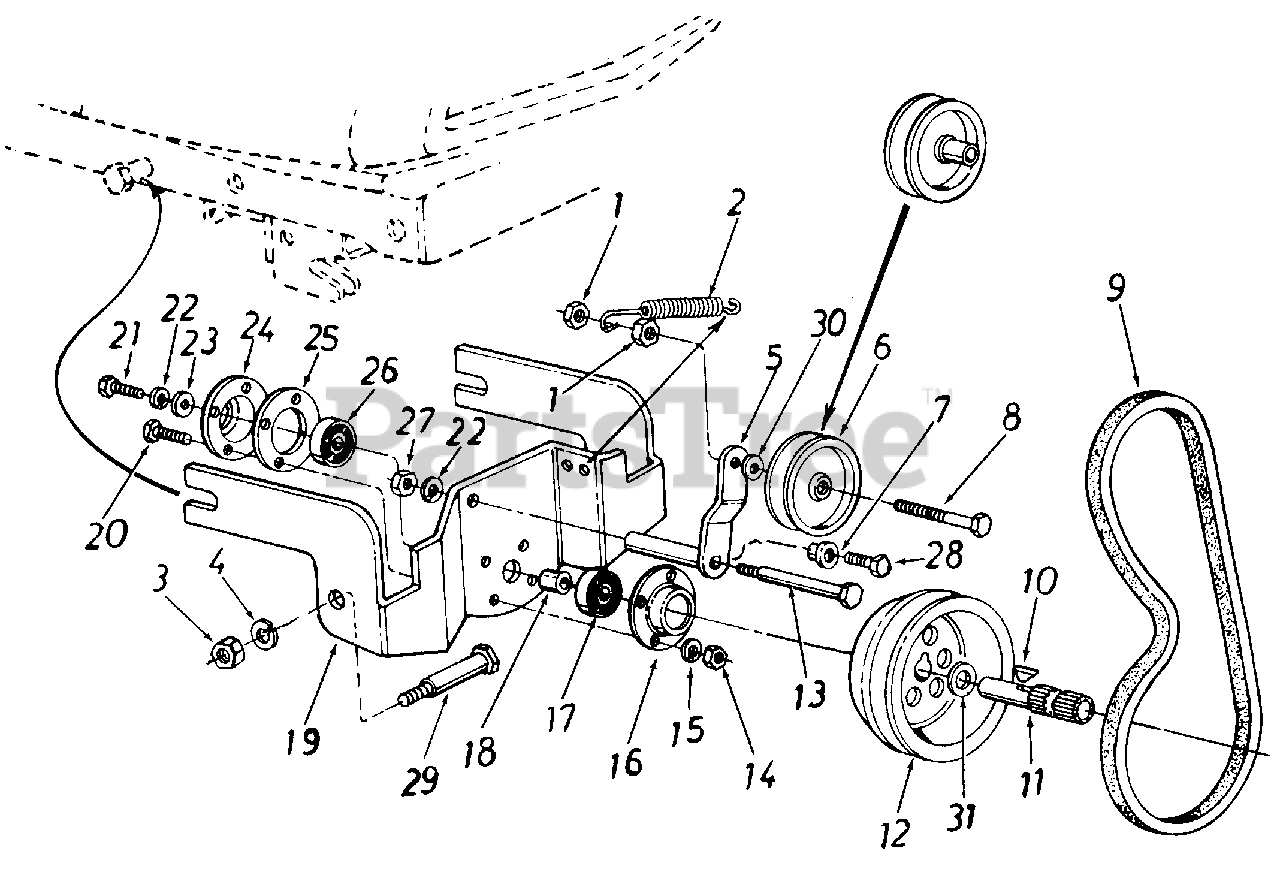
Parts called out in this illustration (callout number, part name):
1	Hex Cent. L.-Jam Nut 3/8-16 Thd.
2	Extension Spring .54" x 5.25" Lg.
3	Hex Jam Nut 3/8-16 Thd.
5	Idler Brk't. 1.5 x 4.5" Lg. (418)
6	Fl.-ldler w/Flanges 2.25" O.D. (418)
7	Shld. Spacer .680 Dia. x .170 (418)
8	Hex Bolt 3/8-16 x 2.00" Lg.*
9	"V"-Belt 1/2 x 37.0" Lg. (418)
10	#9 Hi-Pro Key 3/16 x 3/4" Dia.
11	Spline Shaft 3.94" Lg.
12	5/8" Pulley .790" I.D. x 7.0" O.D. (418)
13	Shoulder Bolt .498" Dia. x 2.0" Lg. (419)
14	Hex Nut 5/16-24 Thd.*
15	L.-Wash. 5/16" I.D.*
16	Bearing Shield
17	Ball Bearing .787" I.D. x 1.85" O.D.
18	Spacer 1.0" O.D. x .790" I.D. x.350" Lg.
19	PTO Support Brk't. (418)
20	Hex Bolt 5/16-24 x 1.00" Lg.*
21	Hex L.-Bolt 3/8-24 x 1.00" Lg.
22	L.-Wash. 3/8" I.D.*
23	Bell.-Wash. .400" I.D. x 1.25" 0. D.
24	Open Bearing Housing 1.85" I.D.
25	Reinforcement Plate
26	Ball Bearing .787" I.D. x 1.85"
27	Hex Jam Nut 3/8-16 Thd. (418)
28	Hex Bolt 3/8-16 x 1.0" Lg. (Grade 5)
29	Shld. Bolt. 498" Dia.
30	Fl.-Wash. .38" I.D. x 1.00" O.D.
31	Fl.-Wash. .78" I.D. x 1.59" O.D. (419)
